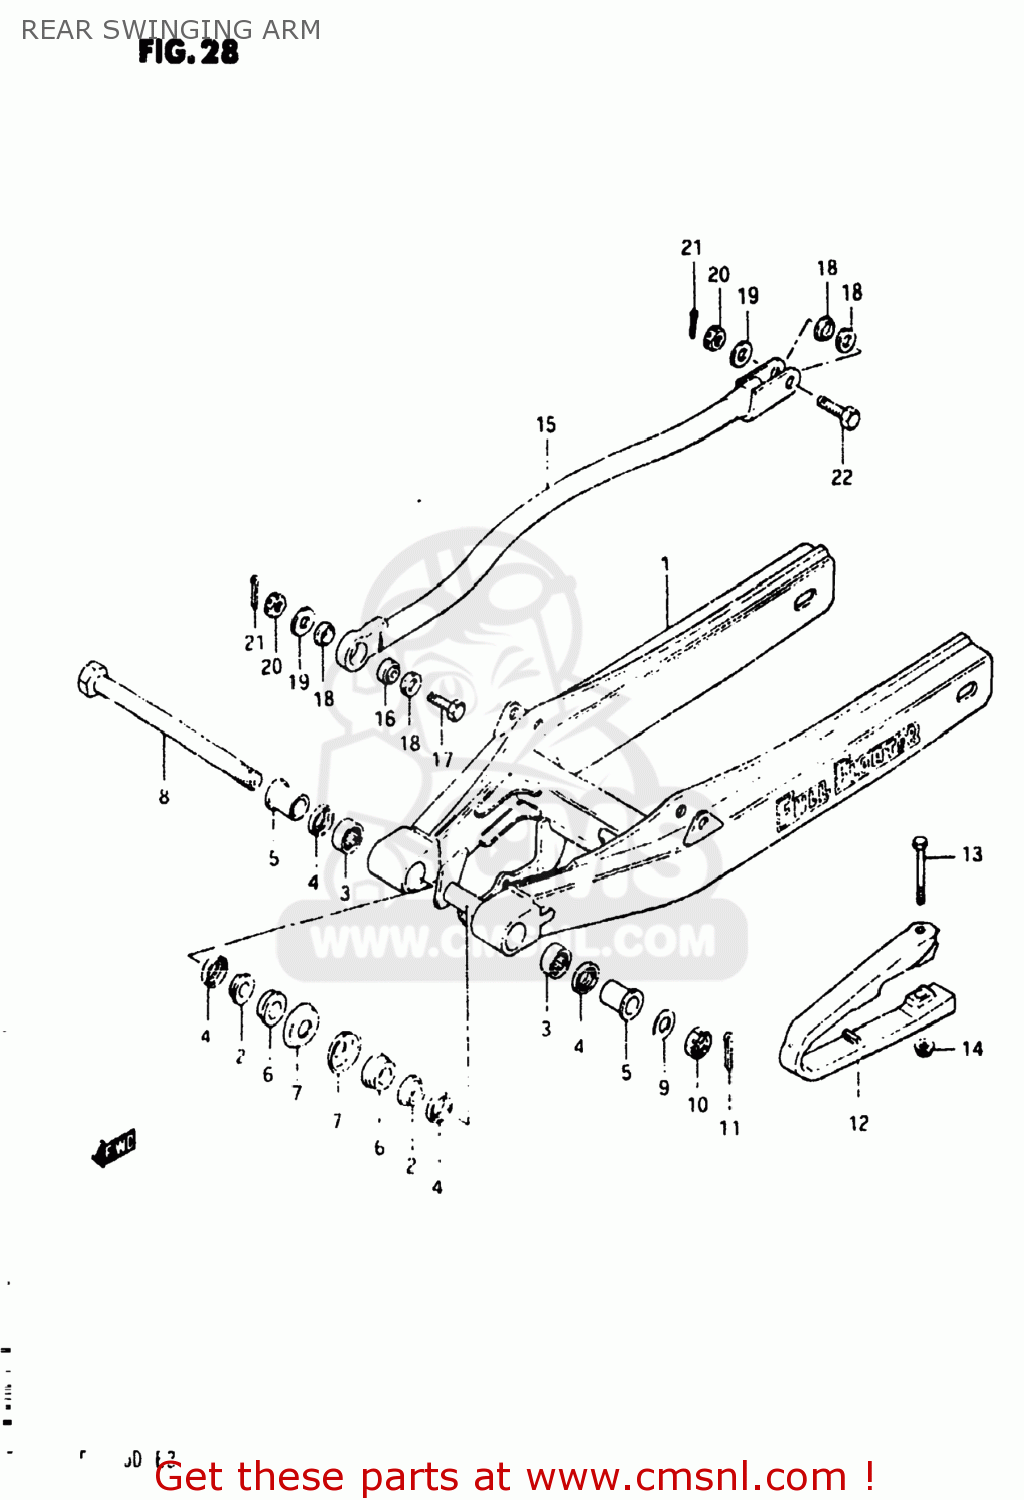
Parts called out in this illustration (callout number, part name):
1	SWING ARM ASSEMBLY,REAR
2	BUSH,RR SWINGINGARM PIVOT
3	BEARING(20X27X20)
4	OIL SEAL
5	SPACER,RR SWGARM PIVOT
6	SPACER,RR SWGARM PIVOT INNER
7	COVER,RR SWGARM DUST SEAL
8	SHAFT,RR SWINGINGARM PIVOT
9	WASHER
10	NUT 14MM
11	COTTER PIN
12	BUFFER,CHAIN TOUCH DEFENSE
13	BOLT(6X70)
14	NUT
15	TORQUE LINK SET,RR
16	SPHERICAL BEARING,TORQUE
17	BOLT 8X28
18	19
19	WASHER
20	NUT 8MM
21	PIN 20X20
22	BOLT 8X29.5
